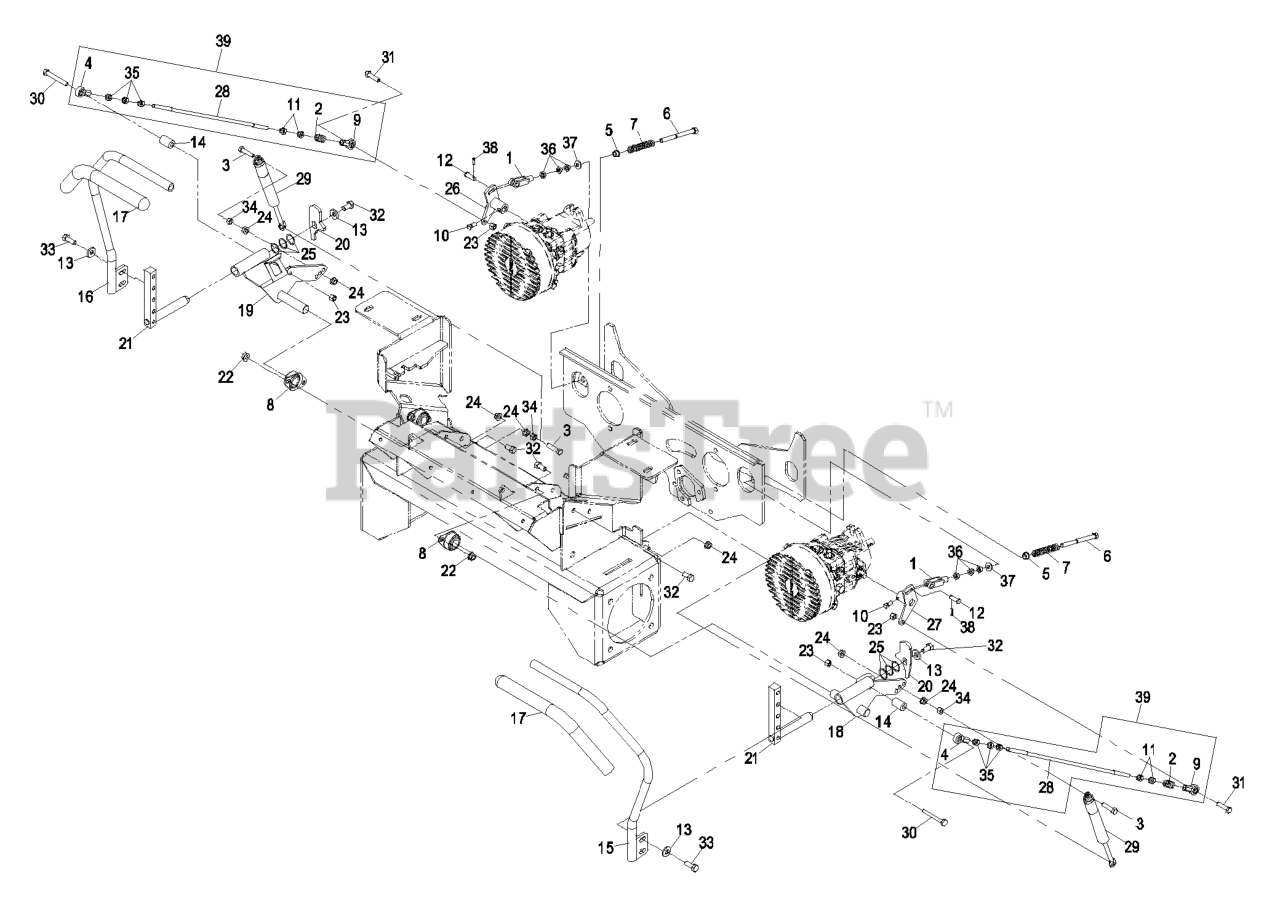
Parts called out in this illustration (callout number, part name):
1	YOKE-ADJUSTABLE
2	SPRING-COMPRESSION
3	SCREW-HH
4	BALLJOINT-RH
5	BUSHING-FLANGED
6	BOLT-RETURN, NEUTRAL
7	SPRING-RETURN, NEUTRAL
8	BEARING-FLANGE, SIDE
9	BALLJOINT-LH
10	SCREW-SET
11	NUT
12	PIN-CLEVIS
13	WASHER-BELLEVILLE
14	SPACER-HYDRO CONTROL, LH
15	ASM,LH LEVER/GRIP
16	ASM.RH LEVER/GRIP
17	GRIP,CONTROL LEVER
18	WLD,LH FMZ MOTION CTRL (P
19	WLD,RH FMZ MOTION CTRL(PL
20	TAB,FMZ MOTION CNTRL (PLA
21	WLD,FR CONTROL SHAFT(PLTD
22	NUT-HHF, WHIZ
23	NUT-LOCK, NI
26	WLD,PR PUMP CTRL RH
27	WLD,PR PUMP CTRL LH
28	LINK,TRACKING ROD FMZ (PL
29	DAMPER-CONTROL, MOTION
30	SCREW-HH
31	SCREW-HH
32	SCREW-HH
33	SCREW-HH
34	NUT-HEX
35	NUT-HEX
36	NUT-JAM
37	WASHER-FLAT
38	PIN-COTTER
39	ASM,FMZ PR TRACKING ROD
